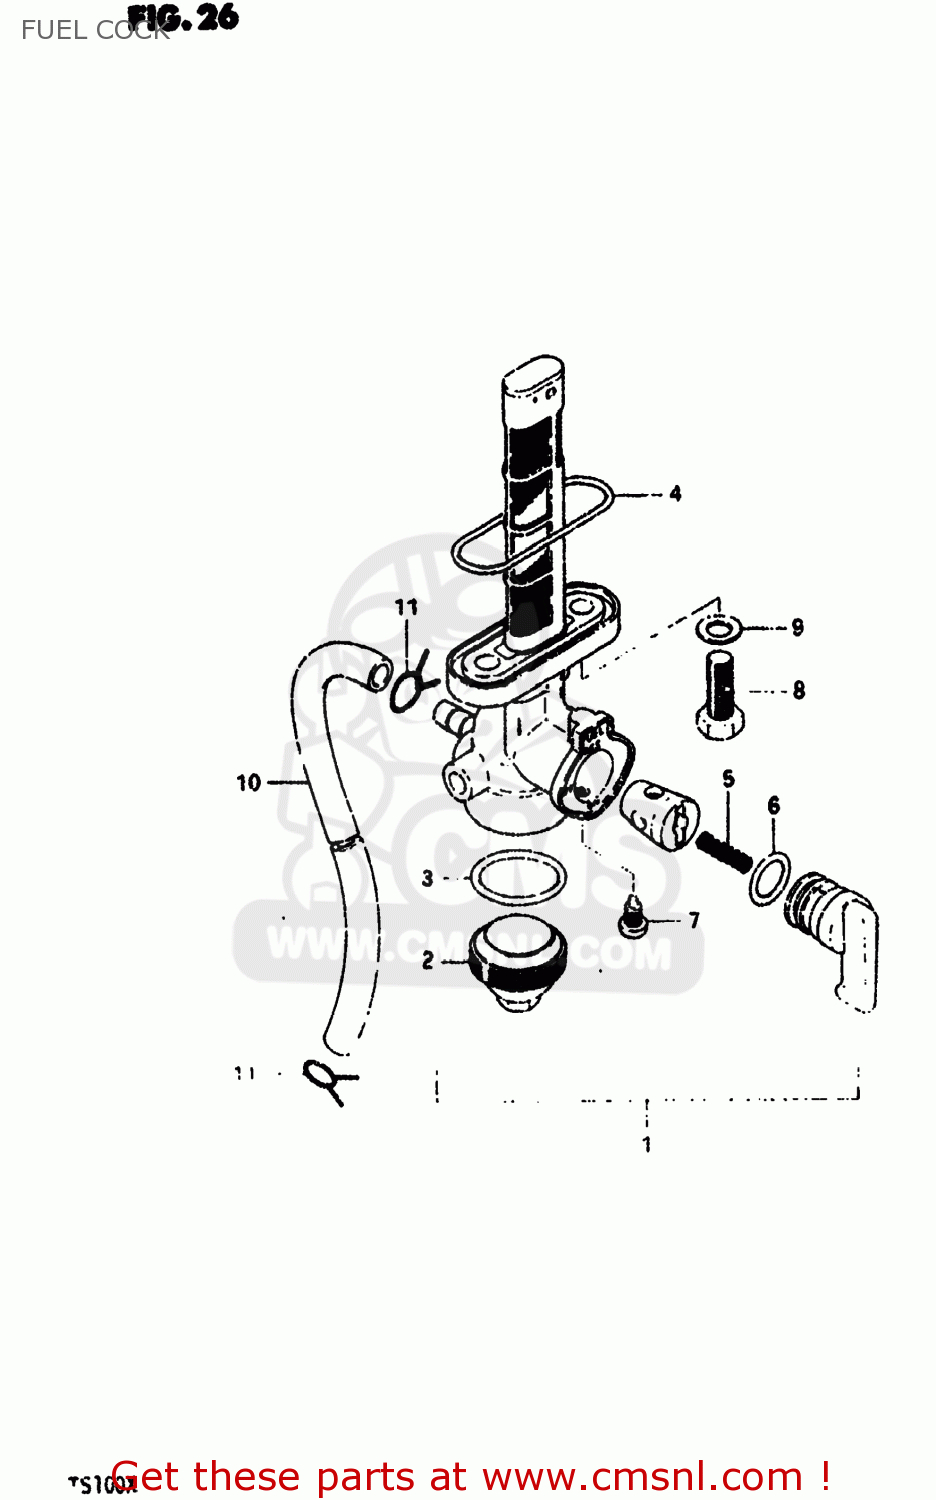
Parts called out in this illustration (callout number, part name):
1	COCK ASSEMBLY,FUEL
2	CUP,STRAINER
3	GASKET,FILTER (NAS)
4	O RING,FUEL COCK
5	SPRING
6	O-RING
7	SCREW
8	BOLT(6X20)
9	GASKET
10	HOSE
11	CLIP
